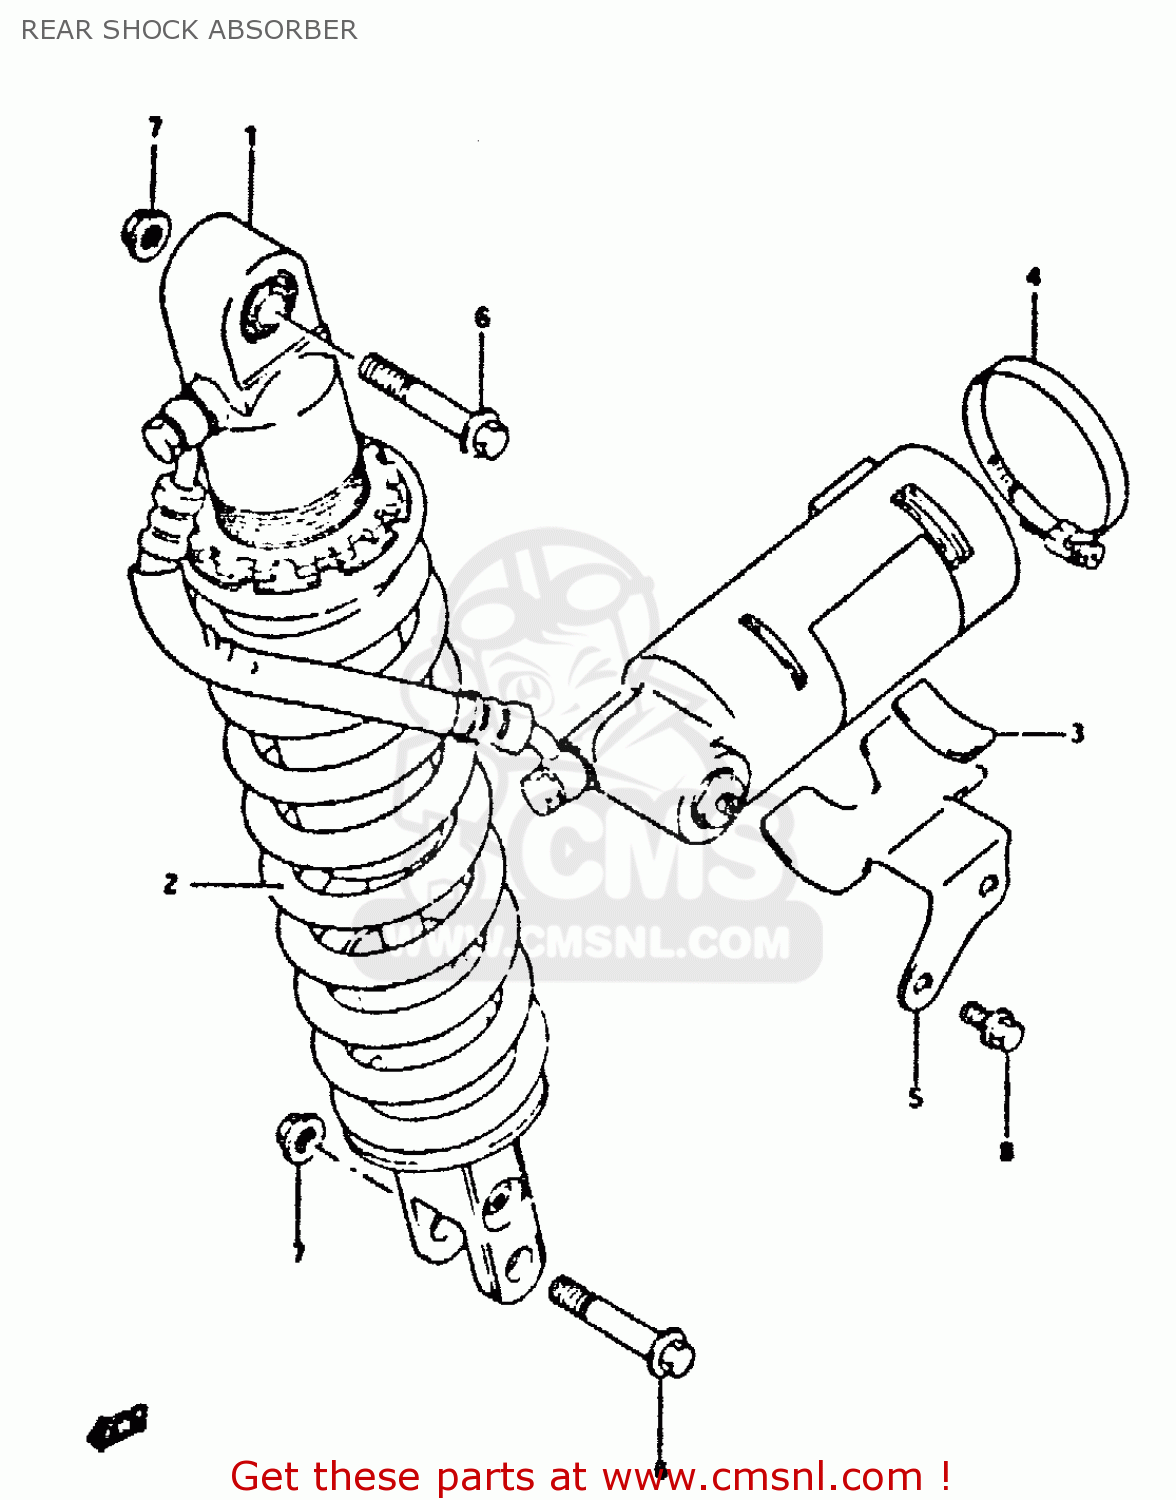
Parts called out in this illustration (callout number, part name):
1	ABSORBER ASSEMBLY,REAR SHOCK
2	SPRING
3	CUSHION
4	CLAMP
5	BRACKET,RESERVOIR TANK
6	BOLT,REAR SHOCK ABSORBER
7	NUT
8	BOLT
